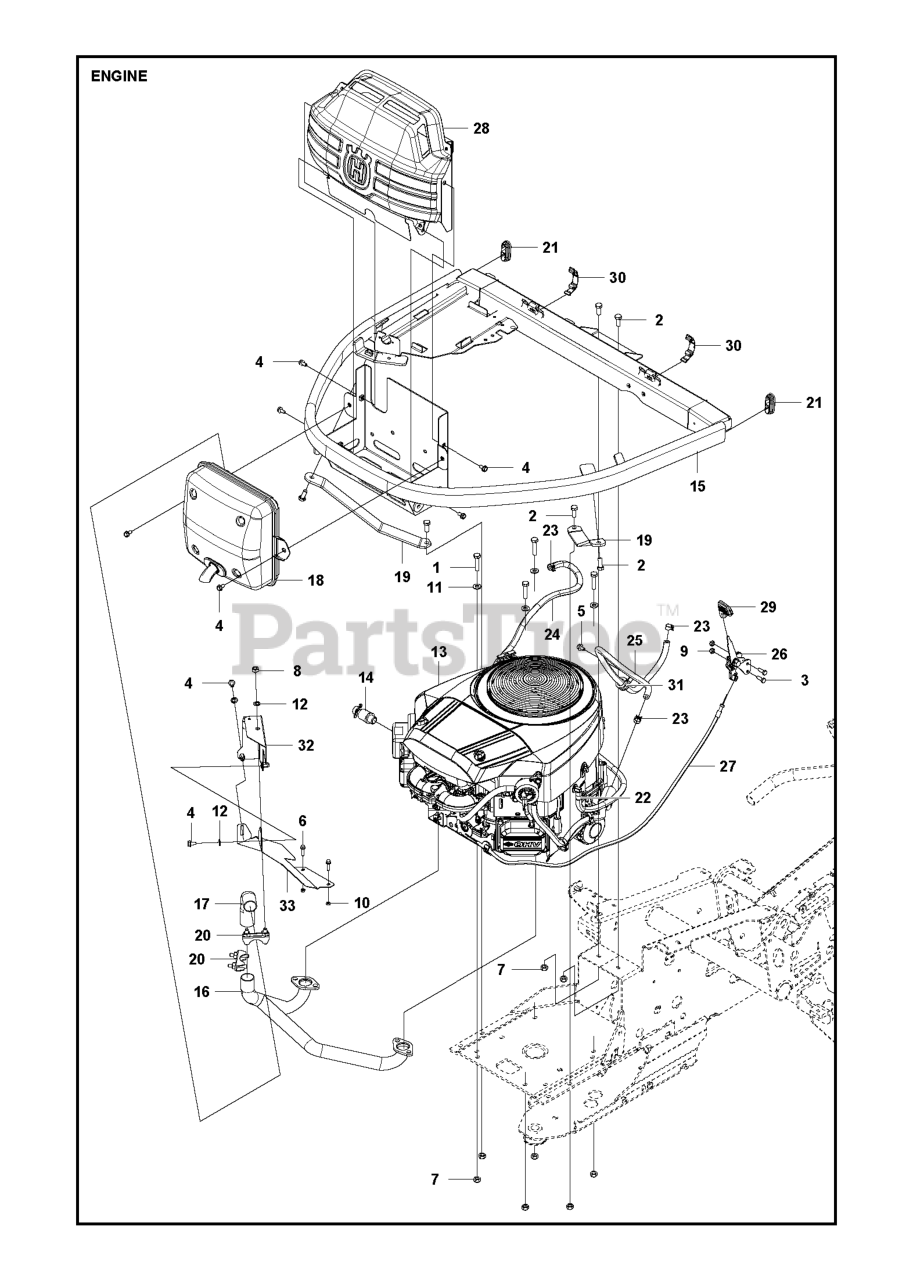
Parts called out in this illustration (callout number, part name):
3	BOLT FLANGE - M6X20
4	SCREW EHHFM
6	SCREW M6S 5X20
7	LOCKNUT M8
8	NUT
9	LOCKNUT M6
10	LOCKNUT M5
11	WASHER BRB 8.4X17
14	VALUE.OIL.DRAIN
20	CLAMP ASSY EXHAUST
22	HOSE CLAMP
31	HOSE CLAMP
